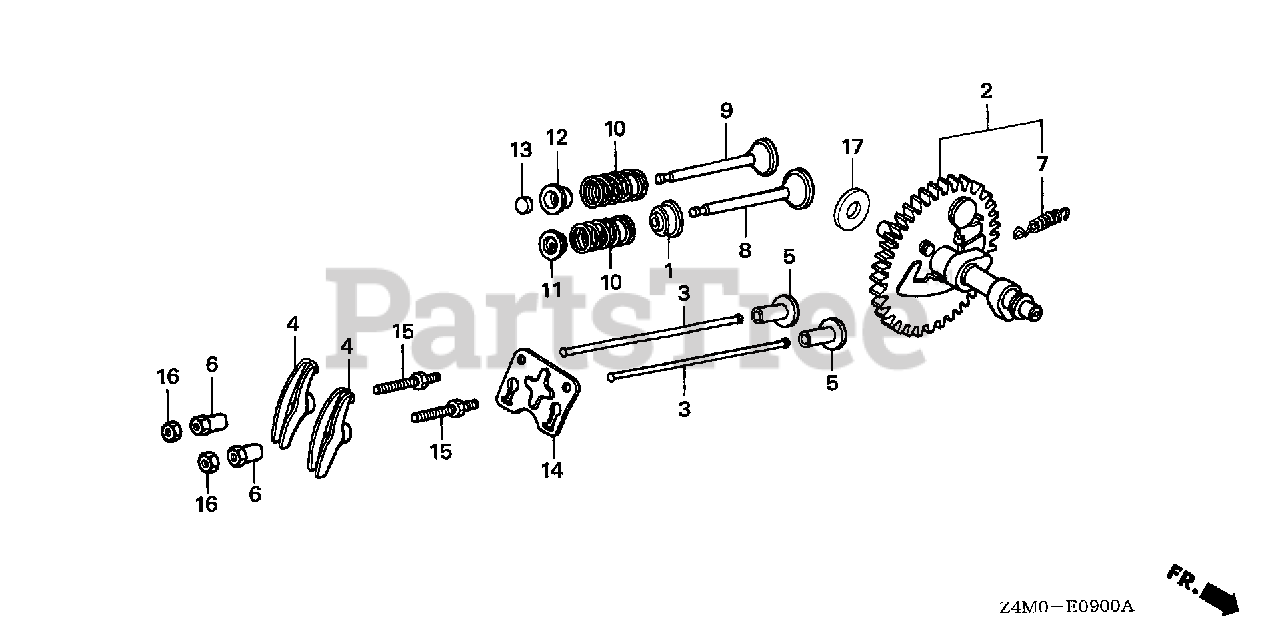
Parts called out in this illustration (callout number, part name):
1	SEAL, VALVE STEM
2	CAMSHAFT ASSY.
4	ARM, VALVE ROCKER
5	LIFTER, VALVE
6	PIVOT, ROCKER ARM
7	SPRING, WEIGHT RETURN
8	VALVE, IN.
9	VALVE, EX. (STELLITE)
10	SPRING, VALVE
11	RETAINER, IN. VALVE SPRING
11	RETAINER, VALVE SPRING
12	RETAINER, IN. VALVE SPRING (EXHAUST SIDE)
12	RETAINER, VALVE SPRING (EXHAUST SIDE)
14	PLATE, PUSH ROD GUIDE
15	BOLT, PIVOT (8MM)
16	NUT, PIVOT ADJUSTING
